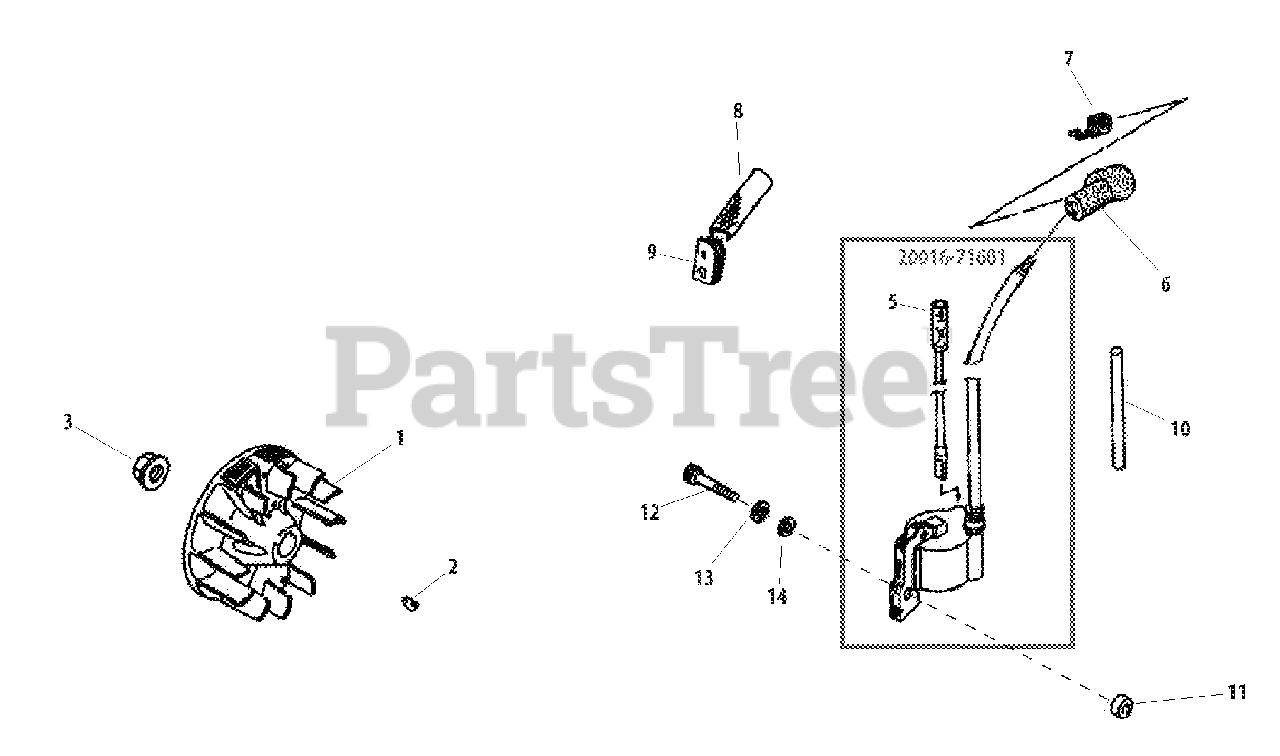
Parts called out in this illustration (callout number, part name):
1	FLYWHEEL
2	KEY, WOODRUFF 3×10
3	NUT M8
5	LEAD
6	CAP, SPARK PLUG
7	TERMINAL, SPARK PLUG
8	TUBE, IGNITION COIL
9	GROMMET
10	TUBE, INSULATOR
11	INSULATOR 4.2×11×6
12	BOLT
13	WASHER, SPRING 4 MM
14	WASHER 4 MM
